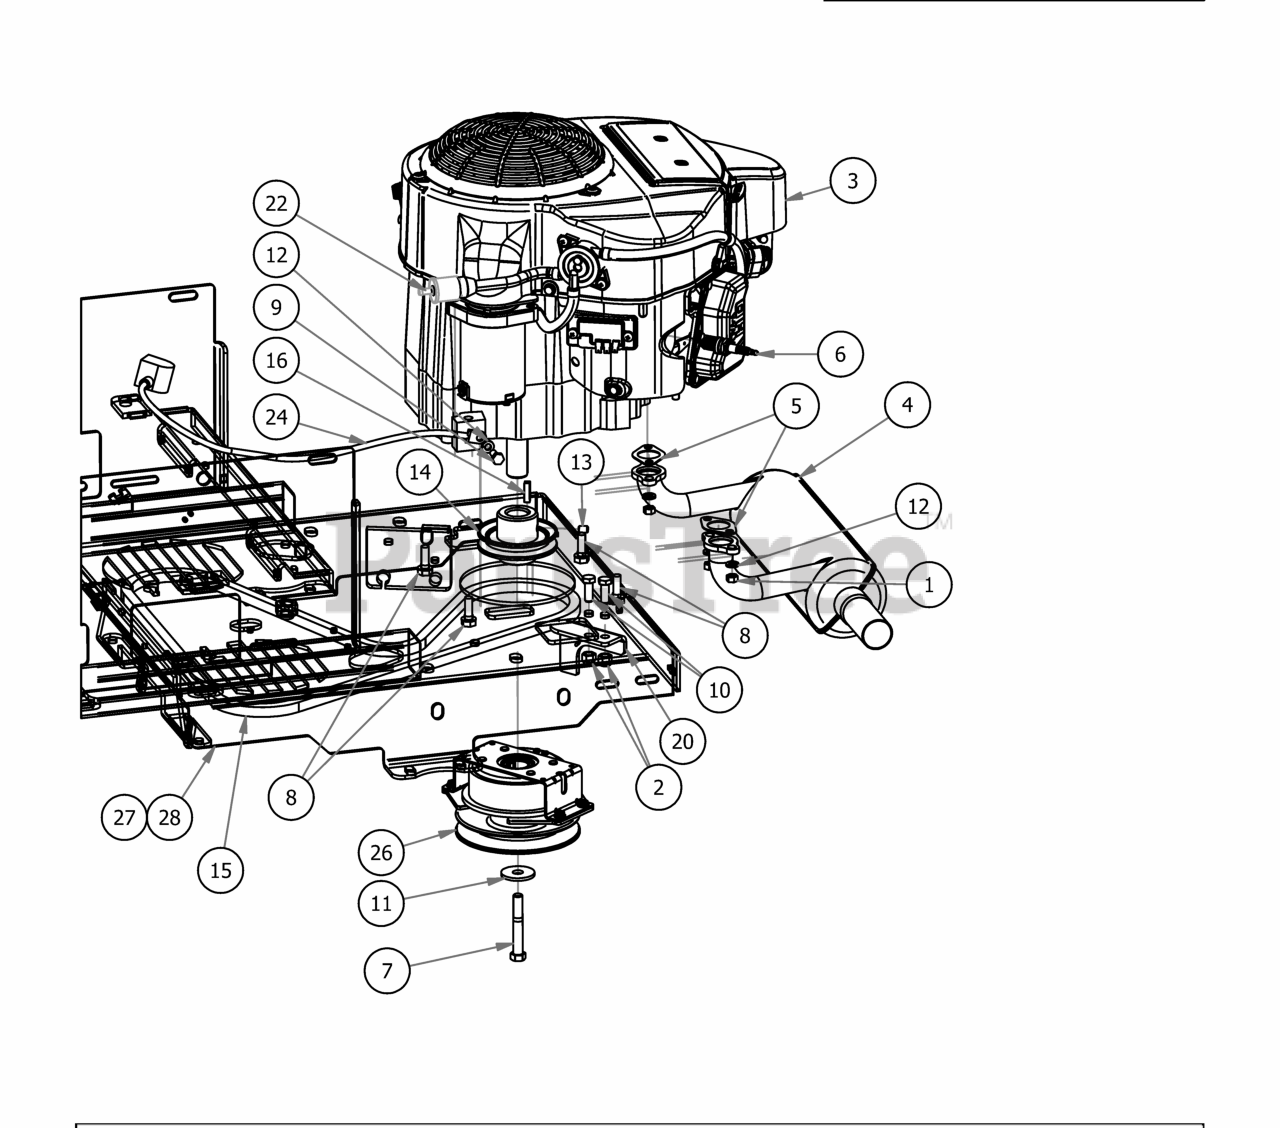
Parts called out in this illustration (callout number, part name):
1	M8-1.25 Zinc Nut
2	3/8 Nylock Nut
3	726cc Kawasaki Engine-FR651V
4	Kawasaki Muffler 1251
5	Exhaust Gasket
6	Spark Plug - Kawasaki
7	7/16"-20 x 3" Hex Bolt Gr. 8
8	3/8 x 1 1/8 bolt
9	M8x1.20x20MM Hex head bolt
10	3/8" x 1" Hex Bolt
11	1/2 Belleville Washer
12	5/16" Lock Washer
13	3/8" Set Screw
14	3-3/4" Motor Pulley
16	1/4" x 1" Key
17	15" Fuel Line Assembly
18	Oil drain Hose
20	2017 MZ Clutch Stop
21	Kawasaki Air Filter
22	Universal Inline Fuel Filter
23	Kawasaki Oil Filter
24	Ground Cable
25	MZ Kohler EPA Canister Assembly
27	2017 MZ/ZT 54"-61" Frame
28	2017 MZ/ZT 42"-48" Frame
29	2017 MZ Magnum Control Panel Assembly
